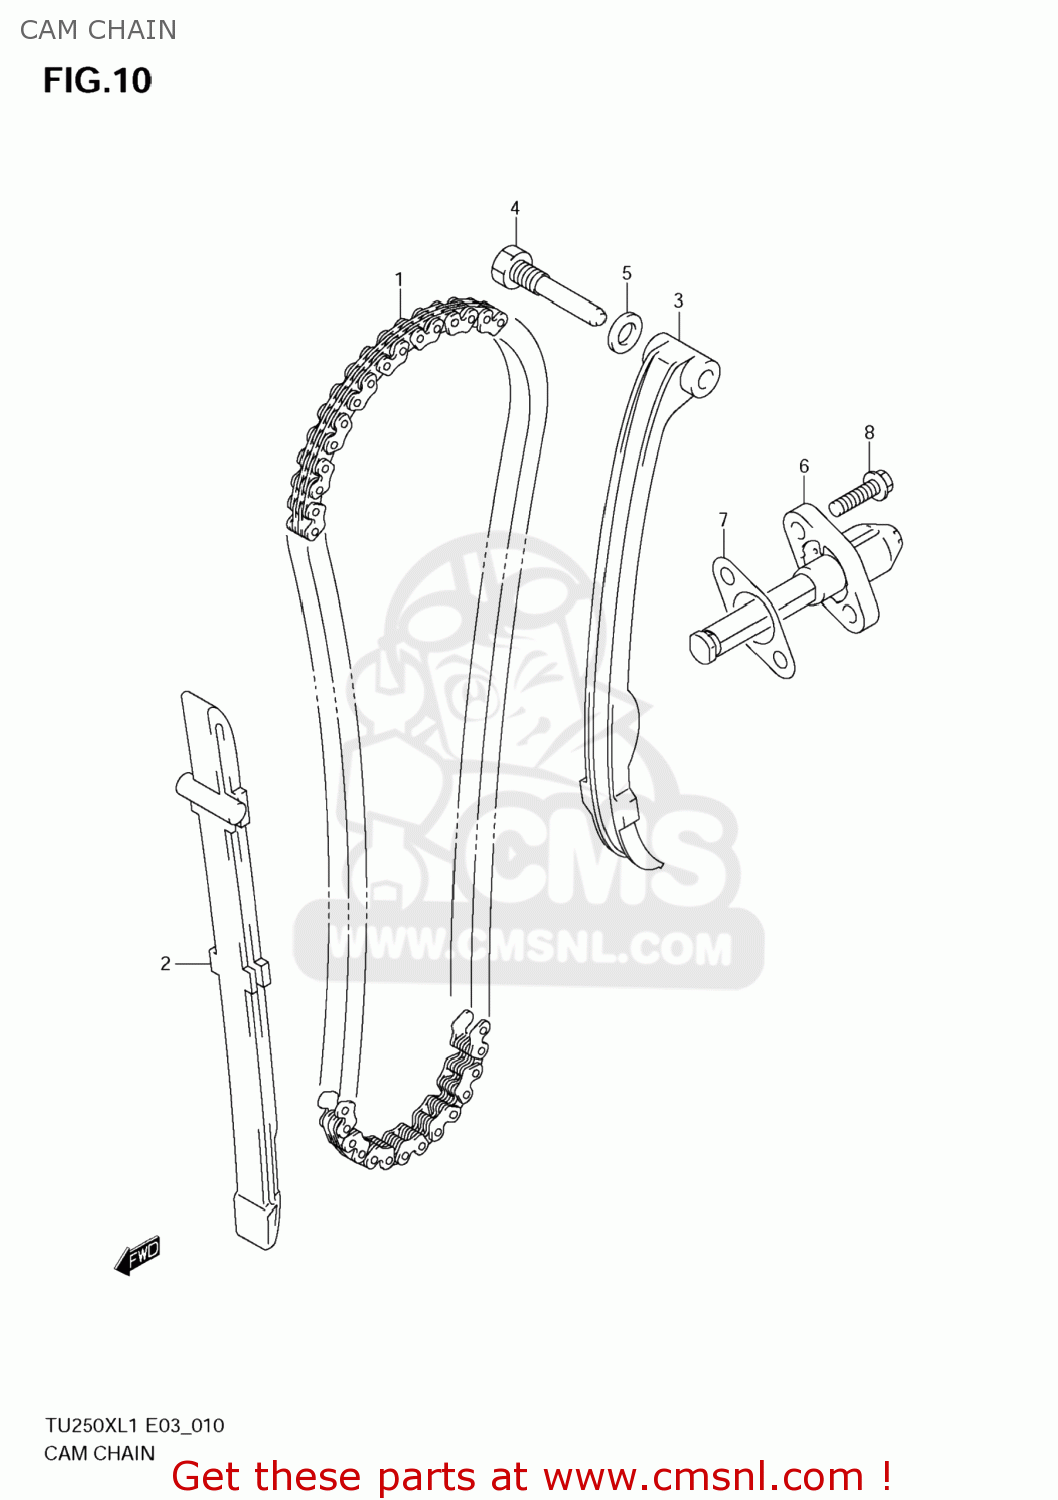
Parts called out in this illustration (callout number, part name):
1	CHAIN,CAMSHAFT DRIVE
2	GUIDE,CAM CHAIN
3	TENSIONER,CAM CHAIN
4	BOLT,CAM CHAIN TENSIONER
5	GASKET(8.2X14X1) (NAS)
6	ADJUSTER ASSY,TENSIONER
7	GASKET,TENSIONER ADJUSTER (NAS)
8	BOLT(6X20)
